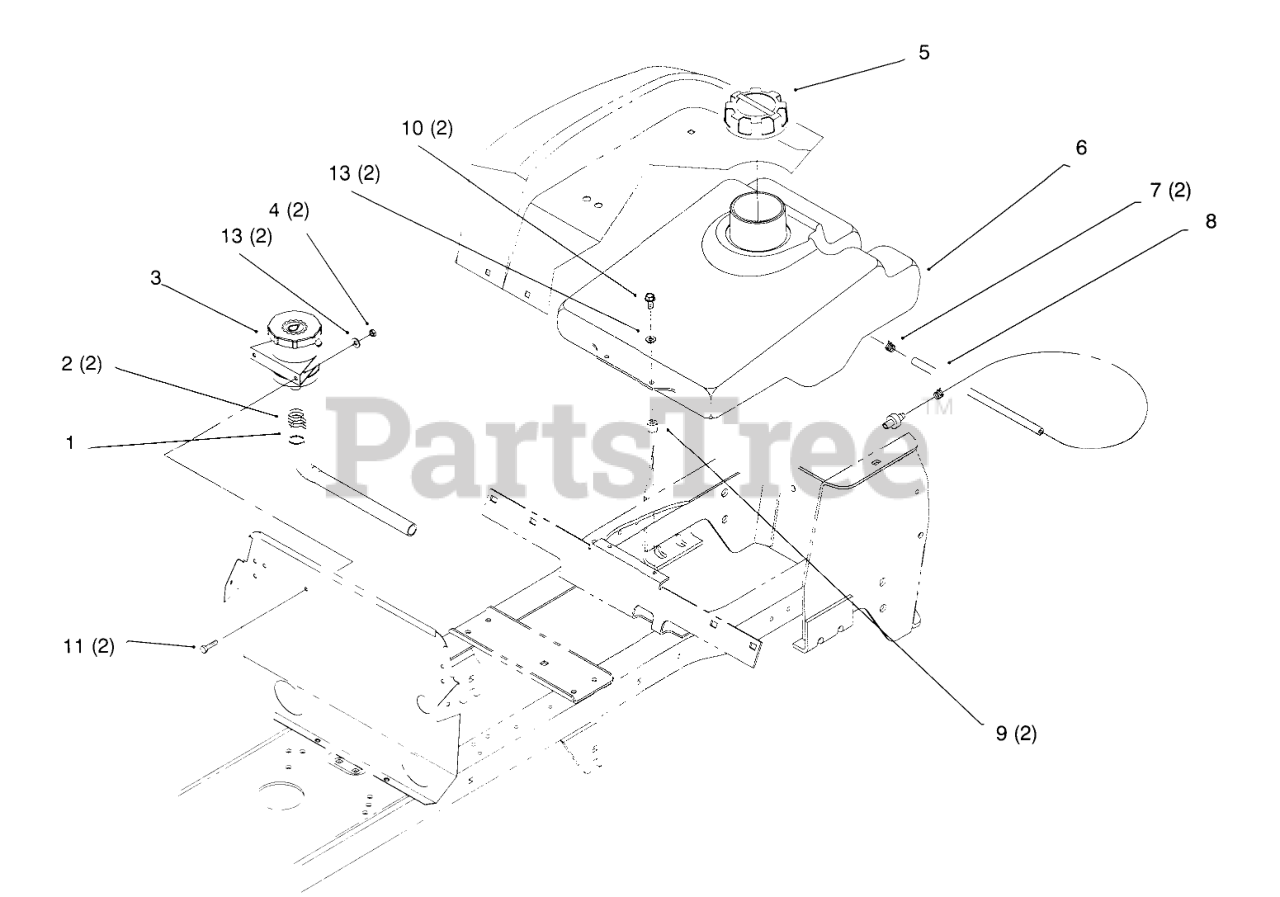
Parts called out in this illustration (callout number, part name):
1	Hose (Only On: 72043,72063,72103)
2	Clamp-Hose (Only On: 72043,72063,72103)
3	Reservoir (Only On: 72043,72063,72103)
4	Nut-Lock (Only On: 72043,72063,72103)
5	GAS CAP ASM
6	Tank-Gas
7	CLAMP-HOSE
8	Hose-Fuel Line (Only On: 72042,72043,72062,72063)
8	Hose-Fuel Line (Only On: 72103)
9	Spacer-Fuel Tank (Only On: 72043,72063,72103)
10	Screw-HHST (Only On: 72043,72063,72103)
10	Screw-TAP (Only On: 72042,72062)
11	Screw-HH (Only On: 72043,72063,72103)
13	Washer-Flat (Only On: 72043,72063,72103)
